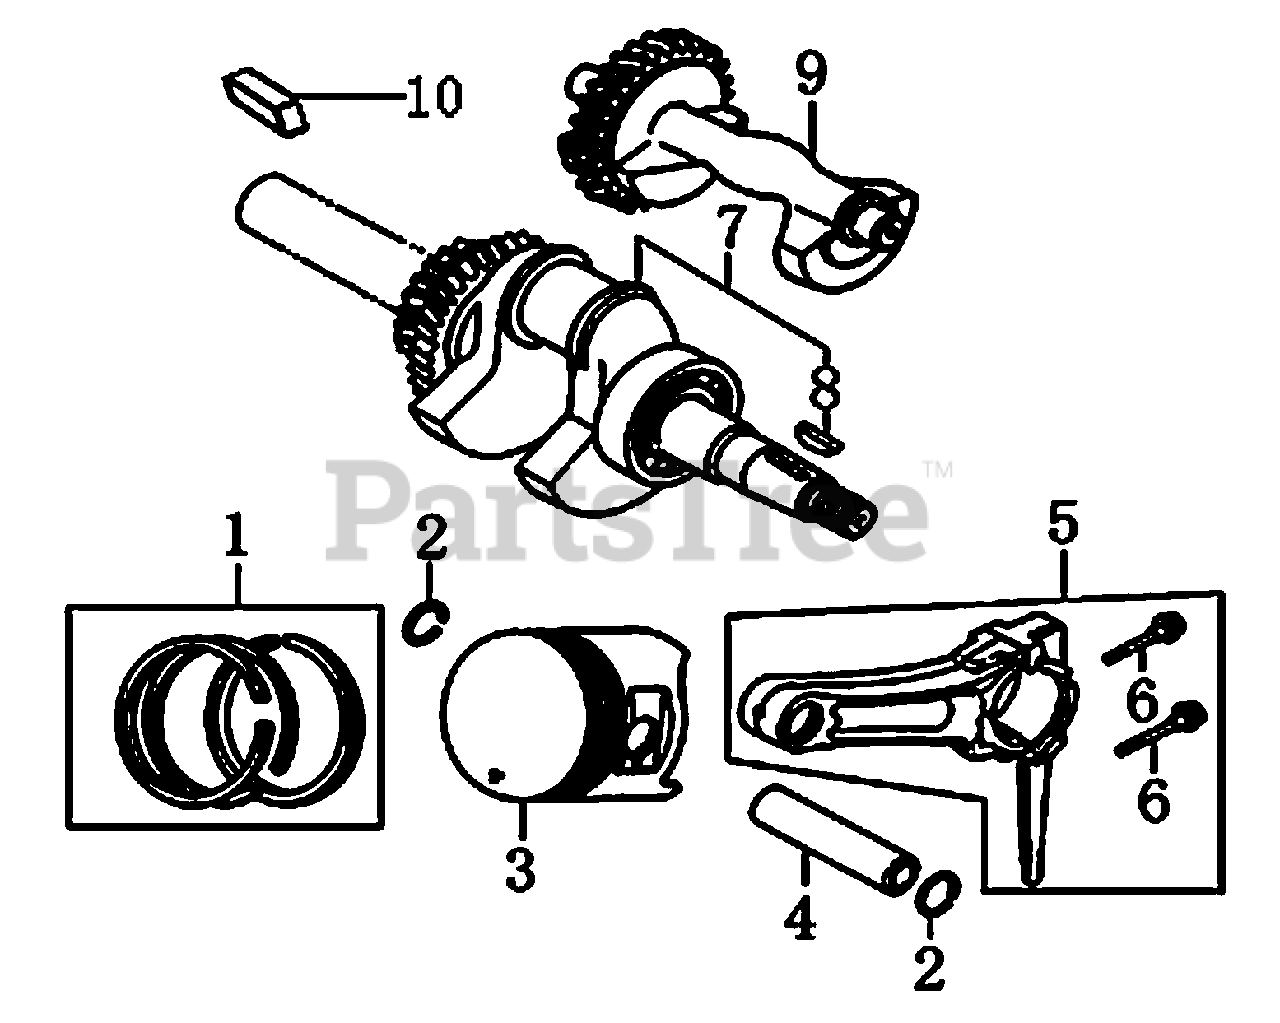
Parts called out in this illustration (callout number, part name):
1	RING SET, PISTON
2	CLIP, PISTON PIN
4	PIN, PISTON
5	CONNECTING ROD ASSY
6	BOLT, CONNECTING ROD
7	CRANKSHAFT ASSY
8	KEY, SPECIAL WOODRUFF
9	WEIGHT, BALANCER
